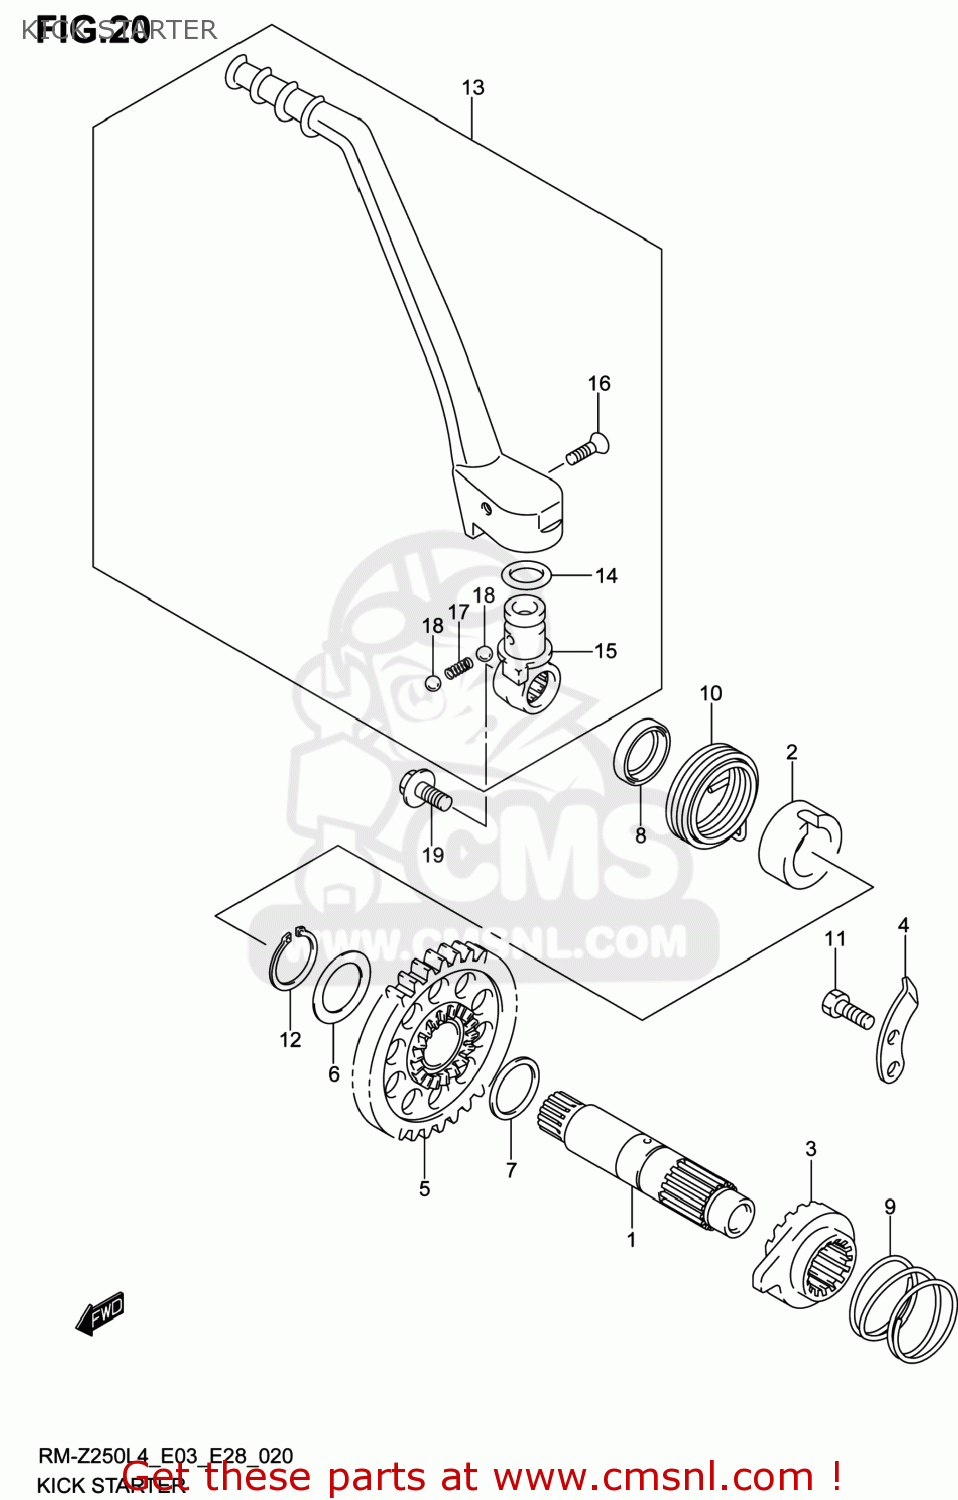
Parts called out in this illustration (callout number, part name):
1	SHAFT,KICK STARTER
2	GUIDE,KICK STARTER SFT SPRING
3	STARTER,KICK
4	GUIDE,KICK STARTER
5	GEAR,KICK STARTER DRIIVE
6	SHIM(18X26X0.5)
7	SHIM(18X22X1)
8	SEAL,OIL(18X30X8)
9	SPRING
10	SPRING
11	BOLT
12	CIRCLIP
13	LEVER ASSY,KICK STARTER
14	O RING,KICK STARTER
15	JOINT,KICK STARTER LEVER
16	SCREW(6X27.5)
17	SPRING
18	BALL
19	BOLT(8X14)
